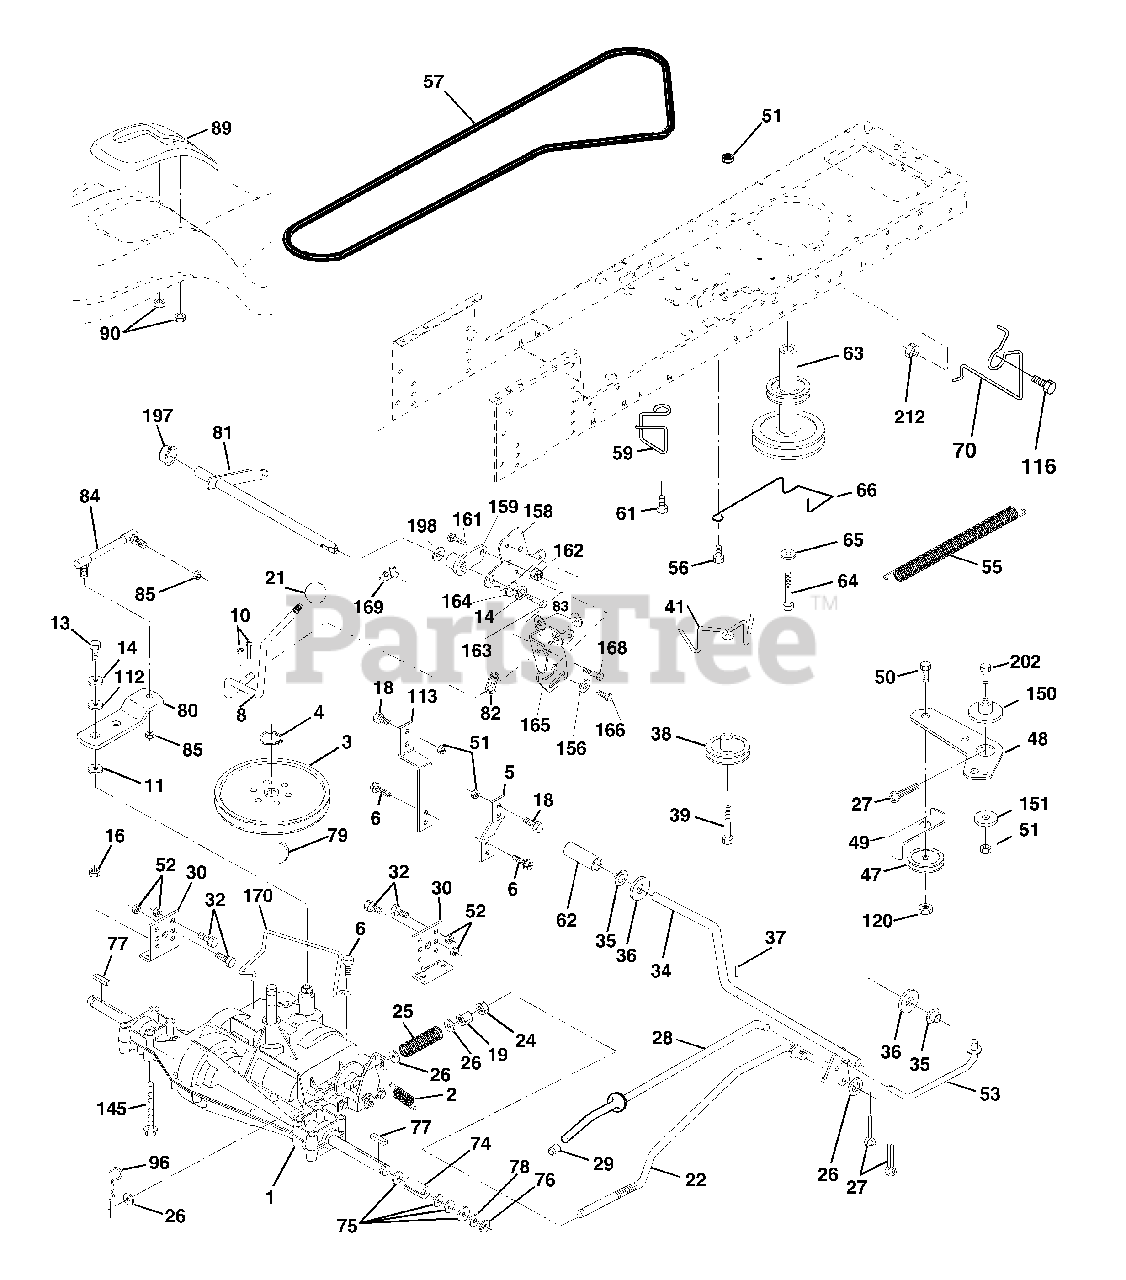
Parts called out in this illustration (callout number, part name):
2	Spring Return Brake T/a Zinc
3	Pulley Transaxle 18" tires
4	Ring Retainer # 5100-62
5	Strap Torque 30 Degrees
6	Screw 5/16-18 X 3/4
8	Rod Shift Fender Adjust Lt
10	Pin Cotter 1/8 X 1 Cad
11	Washer Plate Shf 388 Sq Hole
13	Bolt 1/4-28 Unf Gr 8 W/Patch
14	Washer Lock Hvy Helical
16	Nut Lock Hex w/ins 5/16-18
18	Bolt, Fin Hex 3/8-16 UNC x 1 Gr. 5
19	Nut Lock 3/8-16 Unc
21	Knob
22	Rod Brake Blk Zinc 26 840
24	Nut Hex Jam 3/8-16 Unc
25	Spring Rod Brake 2 00 Zinc
26	Washer 13/32 X 13/16 X 16 Ga
27	Pin Cotter 1/8 X 3/4 Cad
28	Rod Brake Parking LT/YT
29	Cap Brake Parking
30	Bracket Mtg Transaxle
32	Bolt Hex Hd 5/16-18unc X 3/4
34	Shaft Asm Pedal Foot
35	Bearing Nylon Blk 629 Id
36	Washer 21/32 X 1 X 16 Ga
37	Pin Roll 3/16 X 1"
38	Pulley Composite Flat
39	Bolt Fin Hex 3/8-16 unc X 3
41	Keeper Belt Flat Idler
47	Pulley Idler V Groove Plastic
48	Bellcrank Asm
49	Retainer Belt Style Spring
50	Bolt Hex Hd 3/8-16unc X 1-1/2
51	Nut Crownlock 3/8-16 Unc
52	Nut Crownlock 5/16-18 Unc
53	Link Clutch
55	Spring Return Clutch 6 75
56	Screw 3/8-16 x 1-1/4
57	V-Belt Ground Drive 95 25
59	Keeper Belt Span Ctr
61	Screw 3/8-16 x .875
62	Cover Pedal Blk Round
63	Engine Pulley
64	Bolt Hex
65	Washer Lock Hvy Hlcl Spr 7/16
66	Keeper Belt Engine Foolproof
69	Screw Hex wsh Hi Lo 1/4 x 1/2 unc
70	Guide Belt Mower Drive RH
74	Spacer Axle
75	Washer 25/32 X 1 1/4 X 16 Ga
76	E-ring #5133-75
77	Key Square 2 0 X 1845/ 1865
78	Washer 25/32 X 1-5/8 X 16 Ga
79	Key Woodruff #9 3/16 x 3/4
80	Arm Shift
81	Shaft Asm Cross Tapered PMST/20
82	Spring Torsion T/a
83	Washer 17/32 X 3/4 X 16 Ga
84	Link Transaxle PMST/20" Zinc
85	Nut Lock Center 1/4 - 28 FNTHD
89	Console Shift STLT
96	Retainer Spring 1"
112	Washer 9/32 x 3/4 x 10 Ga.
113	Strap Torque LT
116	Bolt Rdhd Sq Neck 3/8-16 x 1
120	Nut Lock Flg. 3/8-16 Unc
145	Bolt Hex FLGHD 5/16-18 Gr. 5
150	Spacer Retainer
151	Washer 13/32 x 2 x 10
156	Washer Srrted 5/16ID x 1.125
158	Bracket Shift Mount
159	Hub Tapered Flange Shift Lt
161	Bolt Rdhd Sqnk 1/4-20 x 3/4 Gr
162	Nut Crownlock 1/4-20 Unc
163	Bolt Hex Fin 1/4-20 Unc x 1 Gr 5
164	Washer 5/8 x .281 x 10 Ga
165	Bracket Pivot Lever
166	Screw 5/16-18 x 5/8
168	Bolt Shoulder 5/16-18 x .561
169	Plate Fastening
170	Keeper Belt Transaxle Gear
197	Nyliner Snap-In
198	Washer Nyliner
202	Bolt Carr Sh 3/8-16 x 1-1/2 Gr. 5
212	Nut Hexflange Lock
